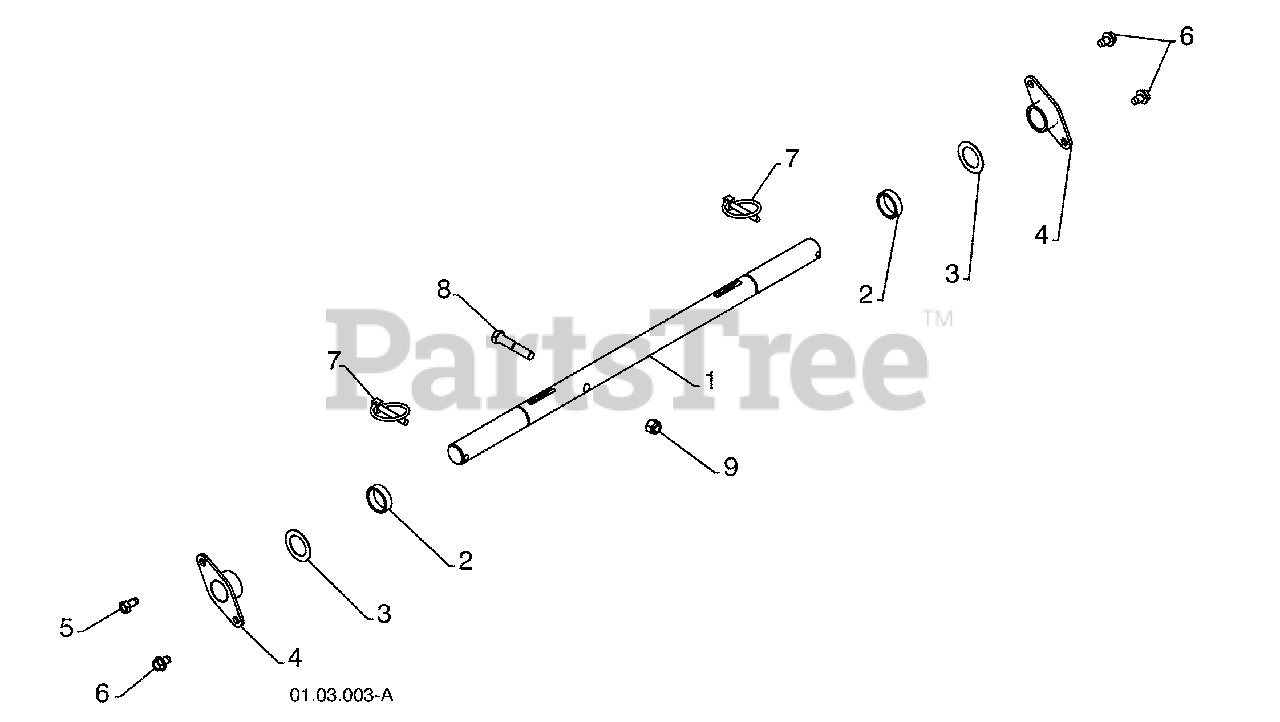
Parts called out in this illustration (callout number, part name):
1	AXLE SHAFT
3	THRUST WASHER
5	SCREW 5/16-18 X .625
6	BOLT 5/16-18 X .500
8	SCREW 3/8-16 X 2.00
9	NUT 3/8-16
